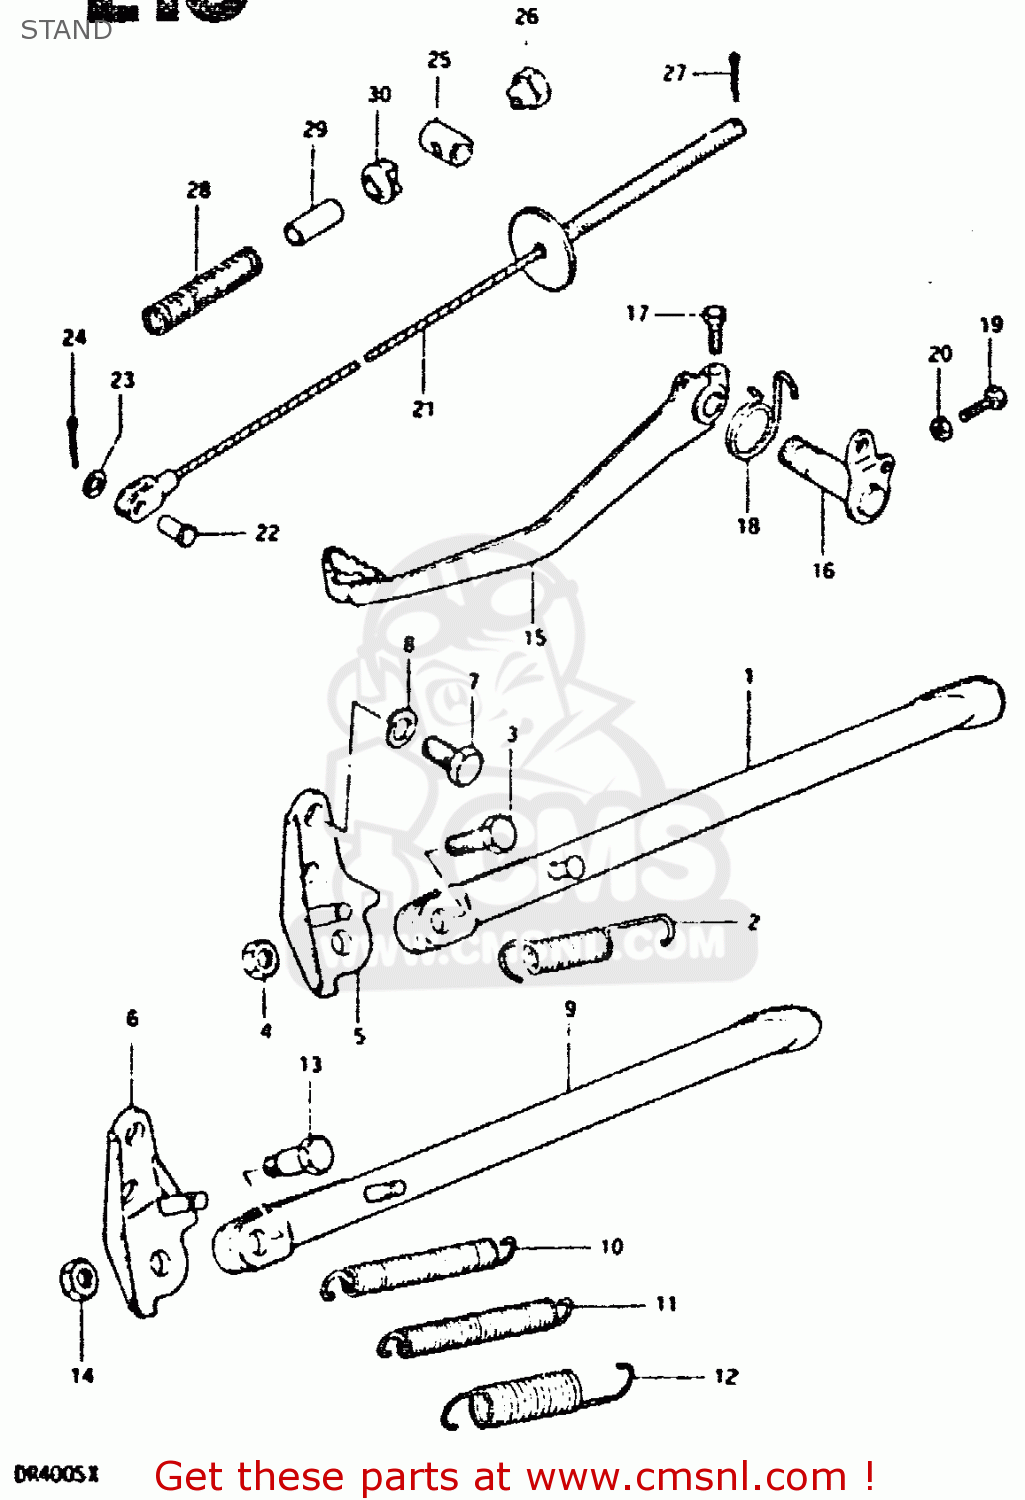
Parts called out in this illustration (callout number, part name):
1	STAND,SIDE
2	SPRING
3	BOLT(10X30)
4	NUT
5	BRACKET,PROP STAND
7	BOLT(10X19)
8	LOCK WASHER
15	PEDAL,BRAKE
16	ARM,BRAKE PEDAL
17	BOLT
18	SPRING
19	BOLT(6X23)
20	NUT
21	CABLE,RR BRAKE
22	PIN(L:17.5)
23	WASHER
24	PIN
25	PIN,BRAKE CABLE ADJUSTER
26	NUT
27	PIN
28	SPRING
29	CUSHION,FR GRILLE,UPPER
30	CUSHION
